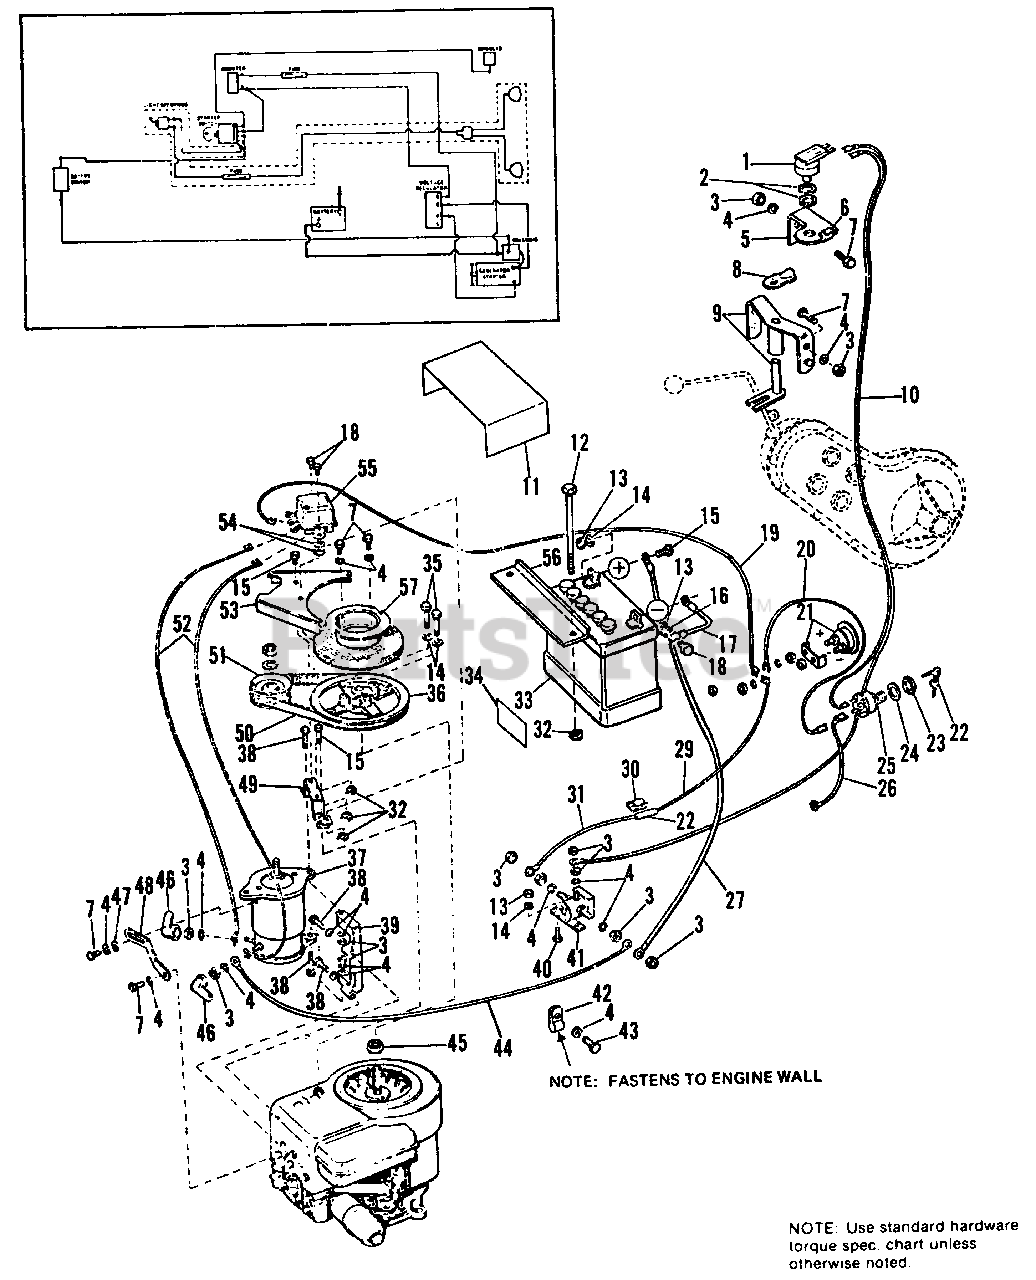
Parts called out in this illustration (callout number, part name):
1	SWITCH, Safety
2	NUT, Hex, Special
3	NUT, Hex, Full, 5/16-18
4	LOCKWASHER, 5/16
5	PLATE, Support
6	CLIP, Speed
7	CAPSCREW, Hex Hd., 5/16-18 x 3/4
8	PLATE, Pivot
9	PIVOT ASSY.
10	WIRE, Safety Switch
11	INSULATION, Battery
12	CAPSCREW, Hex Hd., 1/4-20 x 7
13	NUT, Hex, Full, 1/4-20
14	LOCKWASHER, 1/4
15	CAPSCREW, Hex Hd., 1/4-20 x 5/8
16	LOCKWASHER, Ext., #10
17	CABLE, Ground
18	CAPSCREW, Hex Hd., 1/4-20 x 3/4
20	WIRE, Positive Ammeter to Switch
21	AMMETER
23	NUT, Special
24	LOCKWASHER, Int., 9/16
25	SWITCH, Key
26	WIRE, Switch to Engine Ground
27	CABLE, Battery
28	FUSE, 20 amp
29	WIRE, Negative Ammeter to Solenoid
30	CLIP, Fuse
31	WIRE, Solenoid to Negative Ammeter
32	NUT, Retainer
34	DECAL, Battery
35	CAPSCREW, Hex Hd., 1/4-20 x 2-1/4
36	PULLEY, Electric Starter
37	MOTOR, Generator
38	CAPSCREW, Hex Hd., 5/16-18 x 1-3/4
39	BRACKET, Starter Mounting
40	CAPSCREW, Hex Hd., 1/4-20 x 1/2
43	CAPSCREW, Hex Hd., 5/16-18 x 1/2
44	CABLE, Generator to Solenoid
45	NUT, Flywheel
46	COVER, Terminal
47	WASHER, Plain, 5/16
48	STRAP, Adjustment
49	BRACKET, Regulator
50	V-BELT, Drive
51	PULLEY, Generator
53	GUARD, Pulley
54	WASHER, Plain, 1/4
55	REGULATOR, Voltage
56	CLAMP, Battery
57	PULLEY & SCREEN
